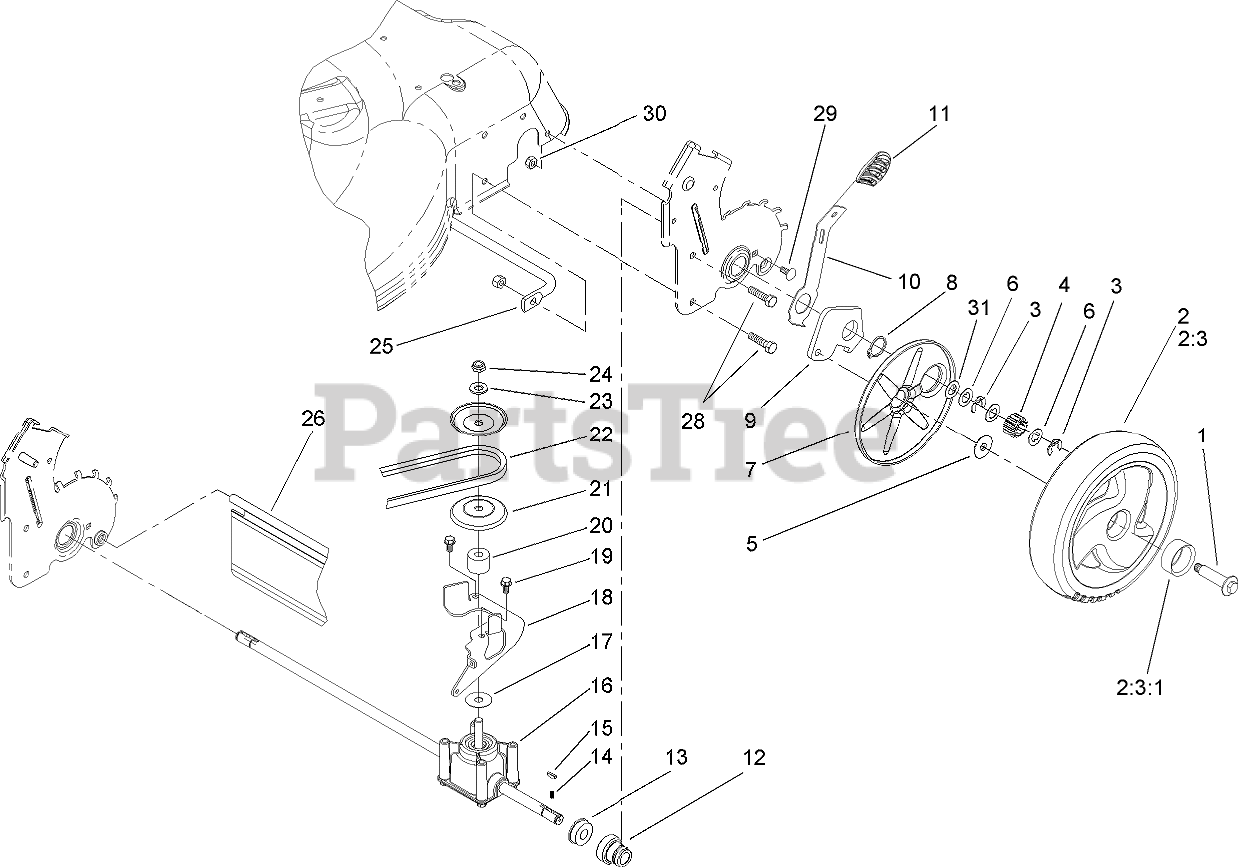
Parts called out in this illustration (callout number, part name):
1	BOLT-SHOULDER
2	Wheel Gear ASM
2:3	WHEEL ASM
2:3:1	BUSHING
3	RING-CLIP, LOCKING
4	Gear-Pinion, 15t
5	WASHER-STEPPED
6	Washer-Thrust
7	COVER
8	RING-RETAINING
9	Arm-Pivot, Rear (LH)
10	Arm-Spring
11	Knob-Lever, HOC
12	RETAINER-BEARING, HOC
13	BEARING-BALL
14	SPRING-COMPRESSION
16	TRANSMISSION ASM
17	WASHER-PLAIN
18	BRACKET-PIVOT, RWD
19	SCREW-HWH
20	SPACER
21	PULLEY-HALF
22	BELT-V
23	WASHER-FLAT
24	NUT-HEX
25	BRACE-PLATE, HOC
26	Shield-Trailing
28	SCREW-HH
29	SCREW-CARR
30	NUT-LOCK, NI
31	WASHER-PLAIN
